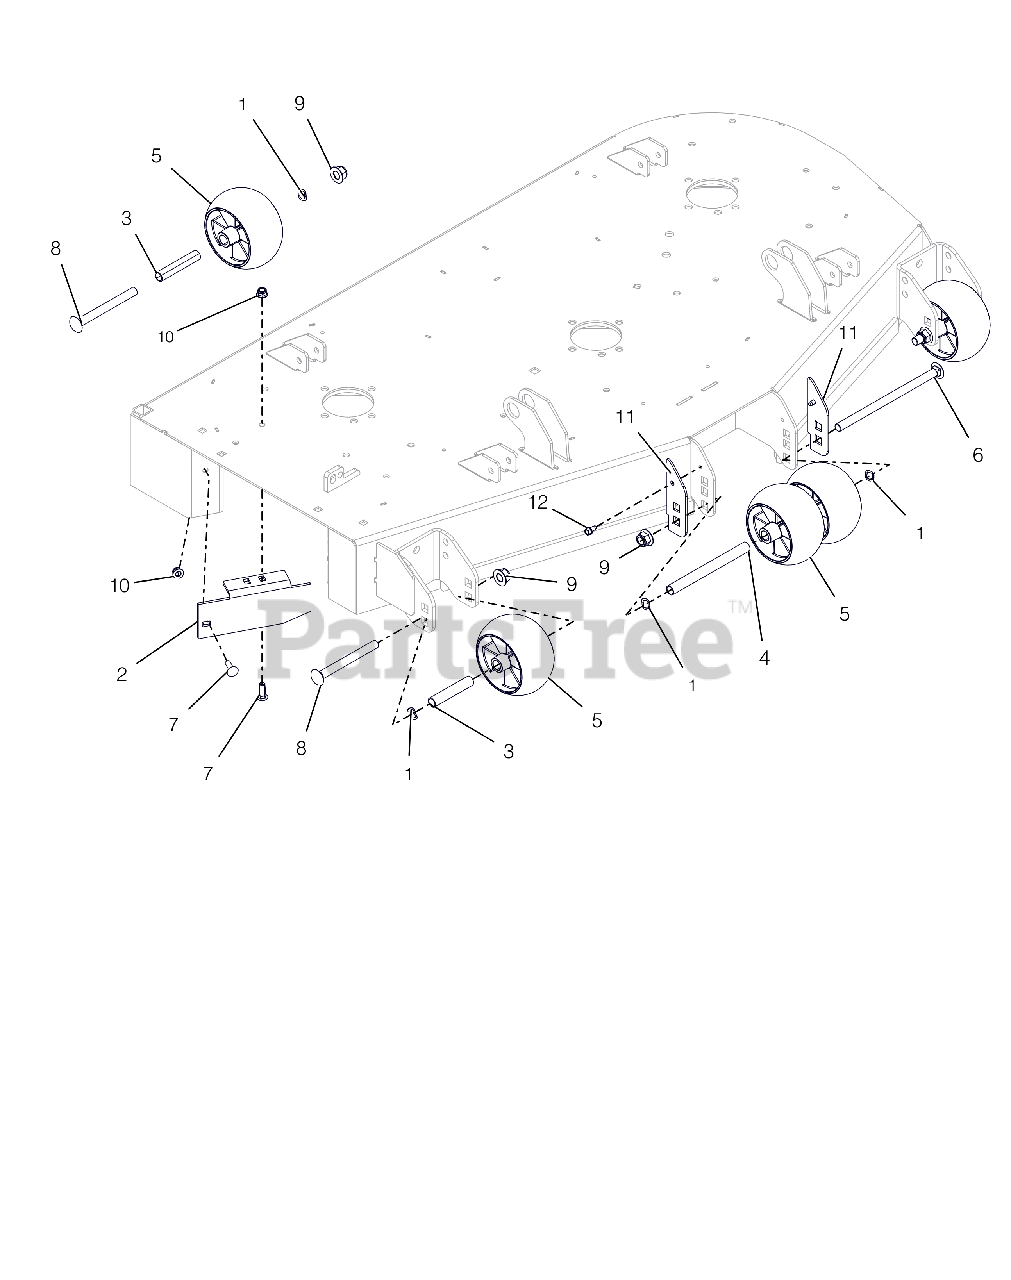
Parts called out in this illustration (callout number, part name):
1	WAVE WASHER .531X.781X.125FH
2	BAFFLE, 44/48" SIDE DISCHARGE
3	SPACER, .510X.625X3.35
4	SPACER, .510X.625X6.50
5	ANTI-SCALP WHEEL - 5X3 CTR
6	@BLT-RDHDSQNK .50-13X8.50 G5YZ
7	@BLT-RDHDSQNK .31-18X1.00 G5YZ
8	BLT-RDHDSQNK .50-13X5.00 GR5YZ
9	@NUT-LK-NYL-FLG .50-13 YWZC
10	@NUT-LK-NYL-FLG .31-18 YWZC
11	PLATE, ANTI SCALP WHEEL EXT.CE
12	SCR-TAP .25-20X.50 HWH TR YWZ
